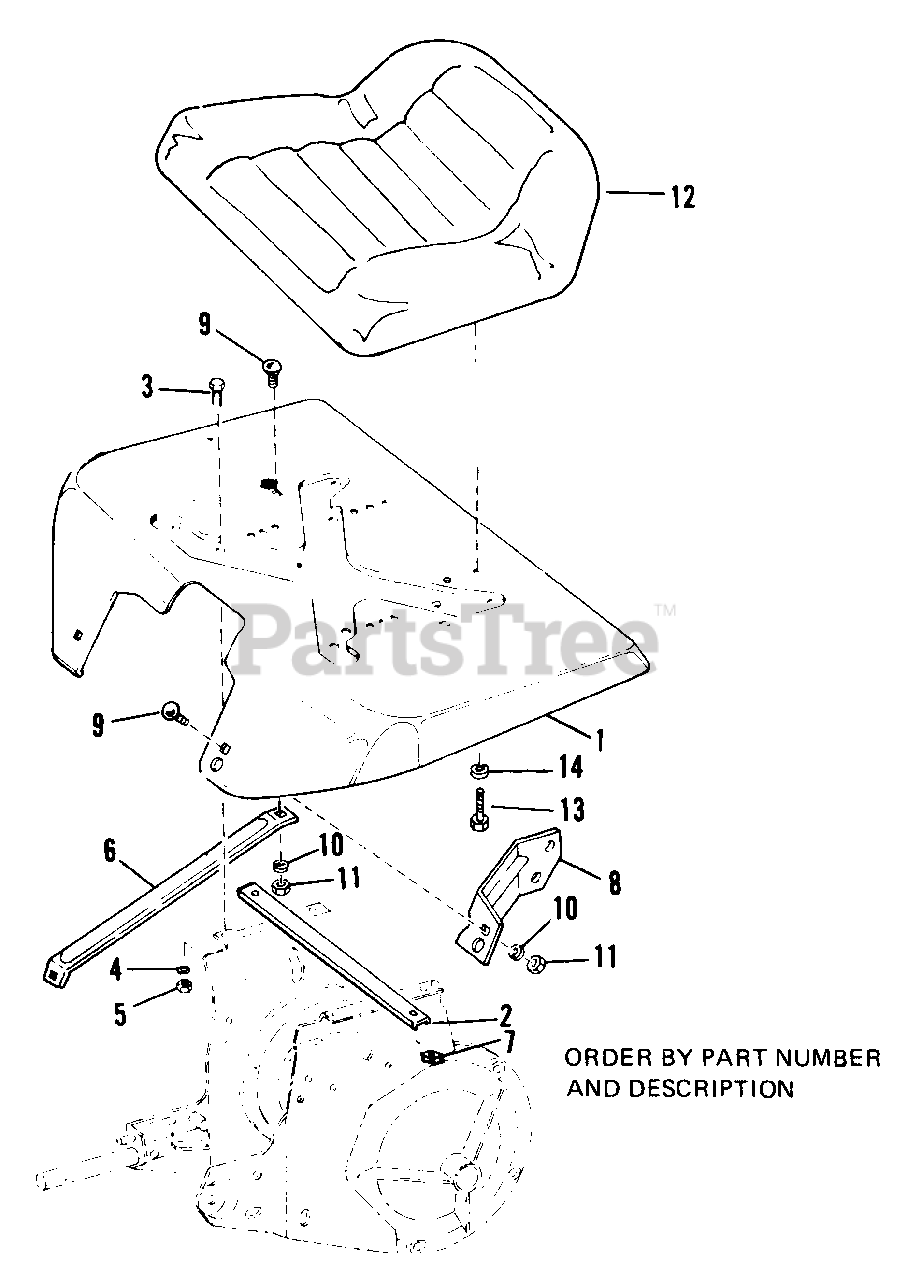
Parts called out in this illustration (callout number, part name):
1	Support, Seat
2	Spacer, Seat Support
3	Capscrew, Hex
4	Lockwasher, 5/16"
5	Nut, Hex, Full, 5/16"-18
6	Brace, Seat Support
7	Nut, Square, 5/16"-18
9	Bolt, Carriage, 5/16"-18 x 1/2" lg.
10	Lockwasher, 5/16"
11	Nut, Hex, Full, 5/16"-18
12	Seat Assembly
13	Capscrew, Hex, 5/16"-18 x 3/4" lg.
14	Lockwasher, 5/16"
